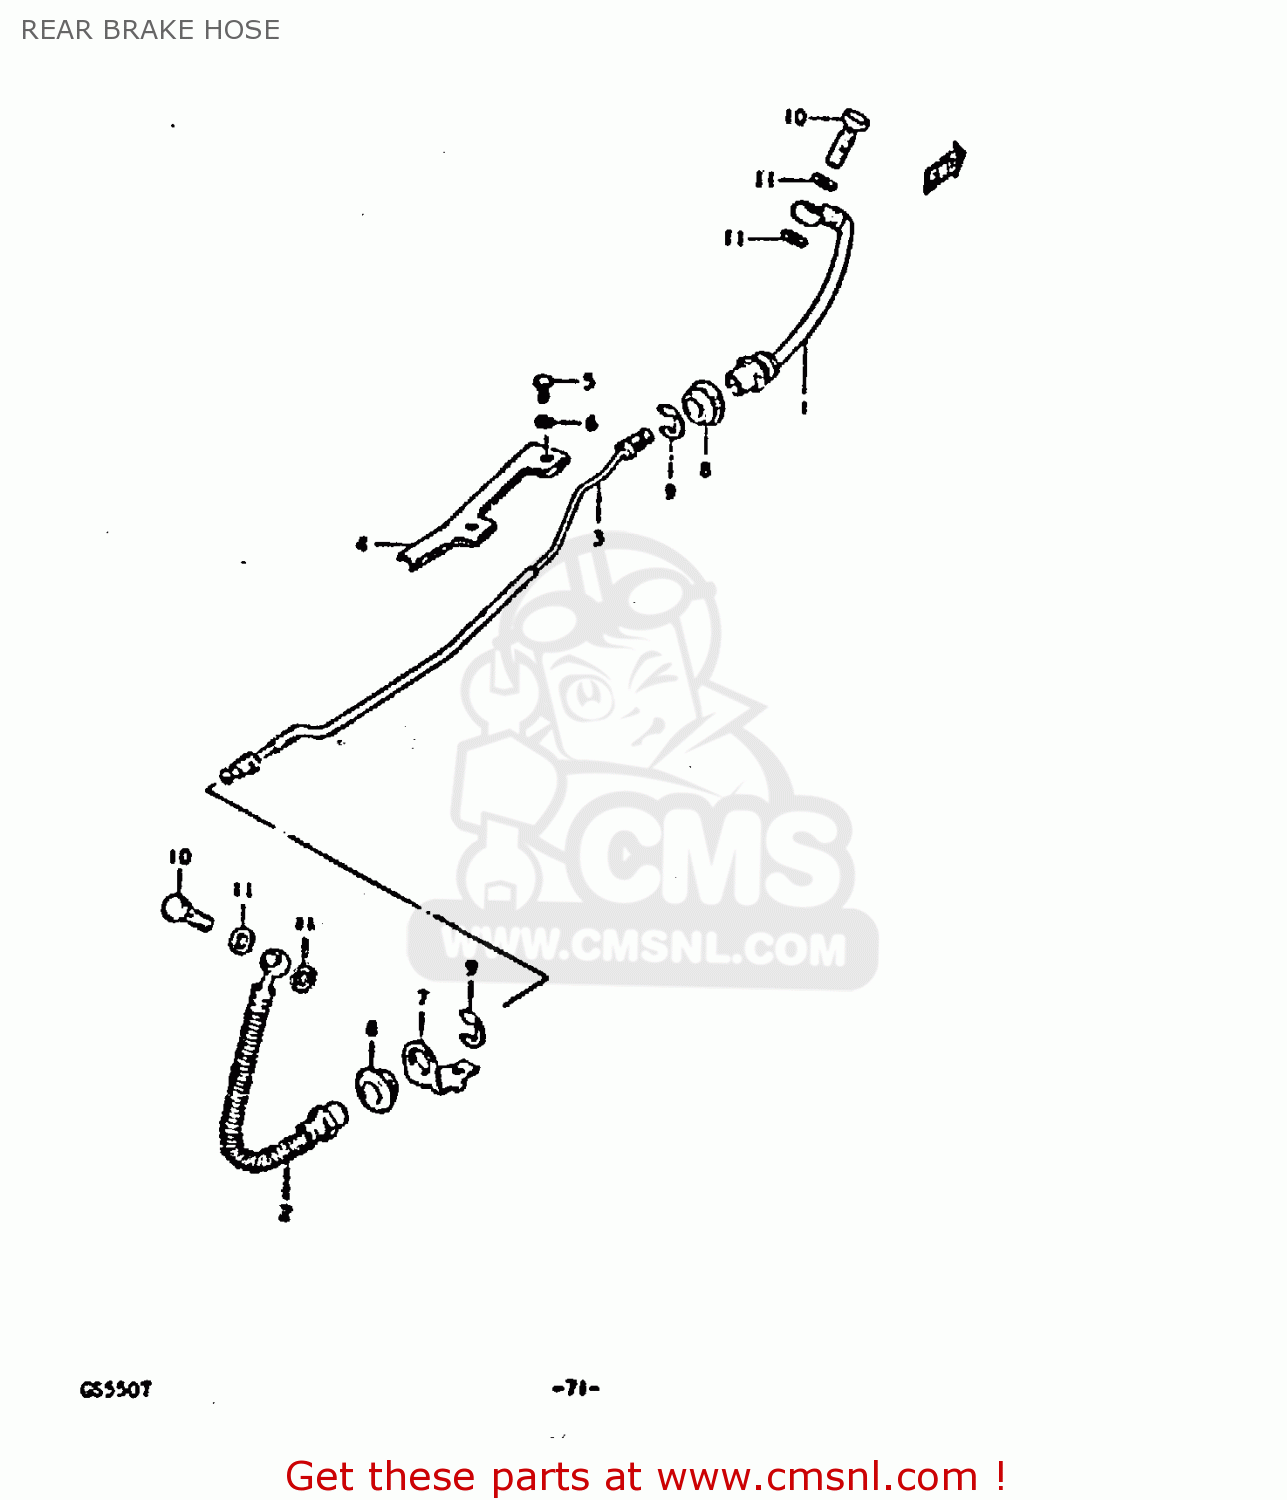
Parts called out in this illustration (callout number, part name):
1	HOSE,REAR BRAKE NO.1
2	HOSE,RR BRAKE NO.2
3	PIPE,REAR BRAKE
4	COVER,REAR BRAKE PIPE
5	BOLT(6X8)
6	LOCK WASHER
7	GUIDE,BRAKE HOSE
8	GROMMET,BRAKE HOSE GUIDE
9	E RING
10	BOLT,UNION
11	WASHER
